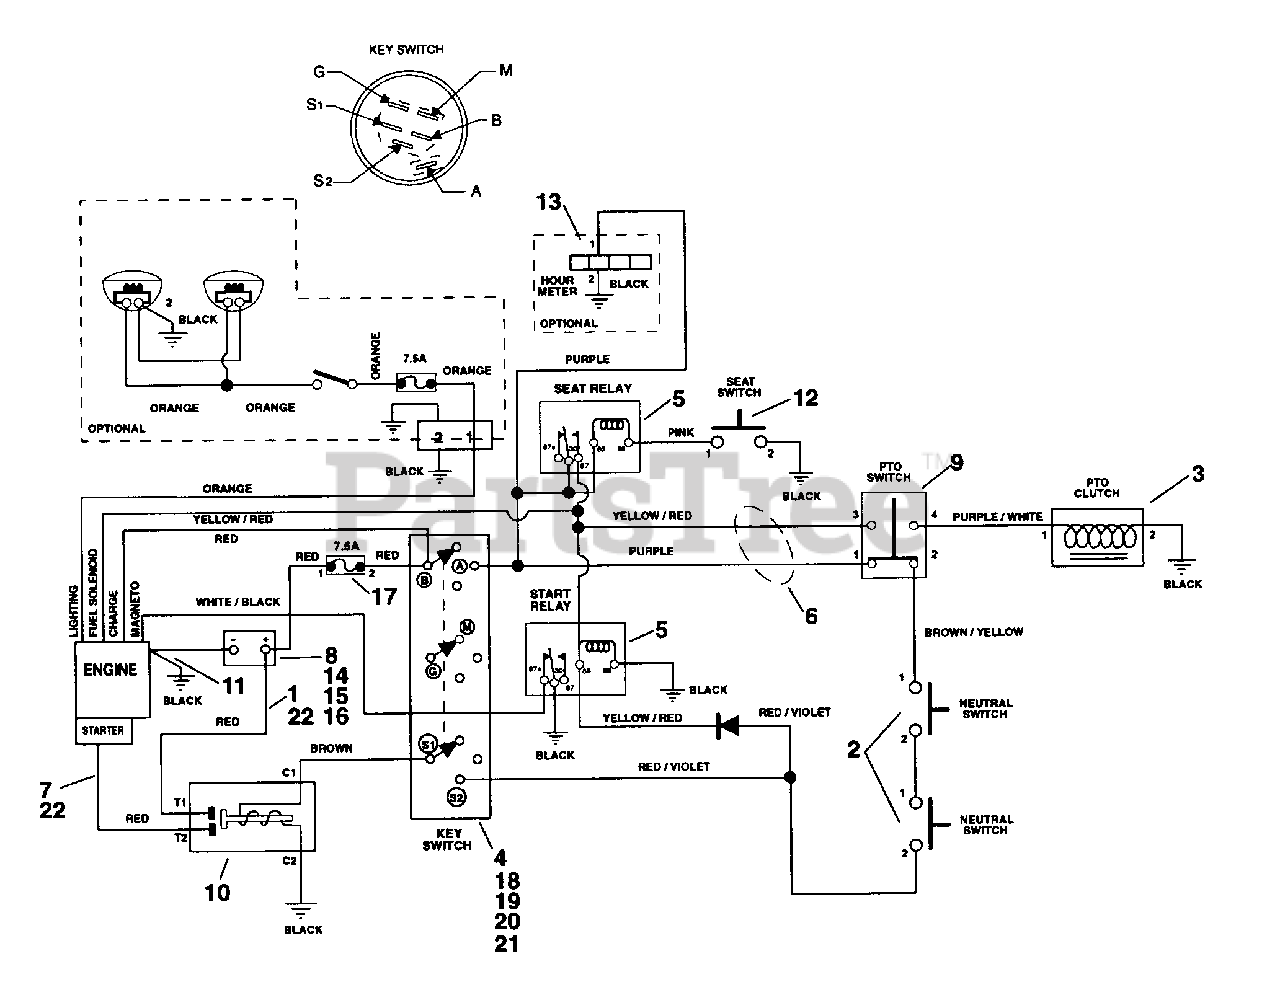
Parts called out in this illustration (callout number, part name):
1	CBL,BATTERY TO SOLENOID
2	SWITCH-NEUTRAL START N.O.
3	ELECTRIC CLUTCH/BRAKE(1.8AMP)
4	KEY SWITCH
5	RELAY
6	WIRE HARNESS 1440
7	STARTER CABLE 6.75"
8	BATTERY W/ TUBE
9	SWITCH, CLUTCH WITH RETAINER
10	SOLENOID
11	GROUND CABLE .31X22.00X.31
12	SWITCH- SEAT
13	HOUR METER
14	RUBBER PAD
15	BATTERY STRAP
17	7.5 AMP Fuse
18	KEY -W/CAP
19	CAP - IGNITION SWITCH
20	NUT- PANEL .562-24 GRECO
21	WSHR-LK-INT .563X.040 PL
22	BOOT, INSULATOR
